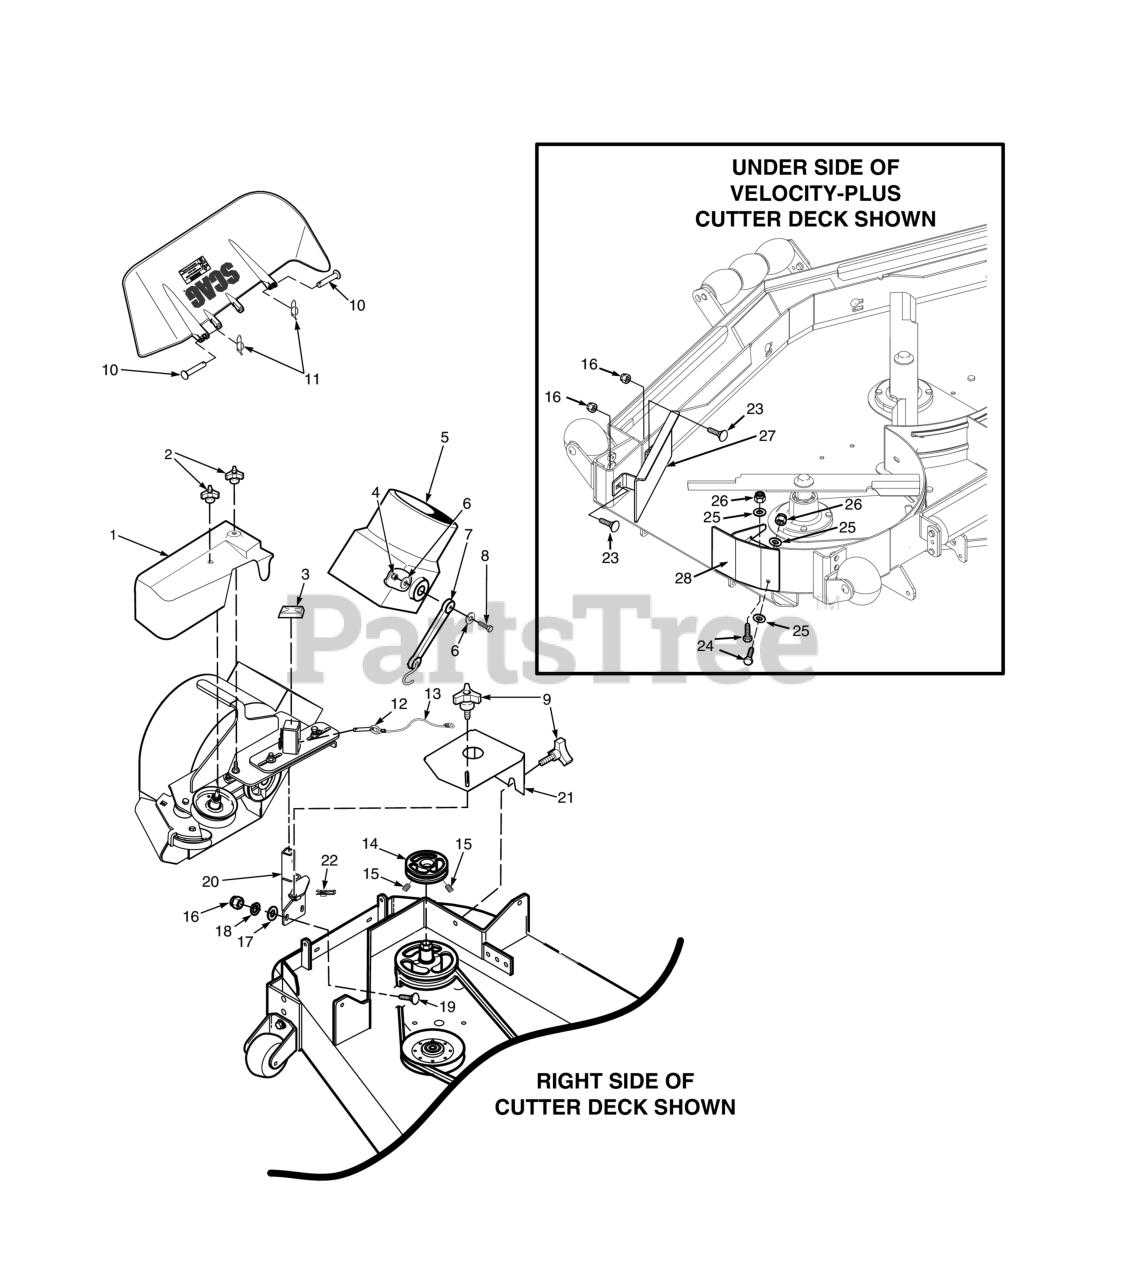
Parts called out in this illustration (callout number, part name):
1	Belt Cover, GC-STT - 61"
2	Wing Nut, 3/8-16 (Small) Top side
3	Cap, Square Vinyl
4	HEX, NUT, ELASTIC STOP LOCK, 1/4-20
5	Adapter, Blower GC-STC,
6	Flatwasher, 1/4" (.312 x .750 x .065")
7	Rubber Strap 7-3/4"
8	SERR. FLG. HEX HEAD CAPSCREW, 5/16-18 X 3/4
9	Knob, w/stud 3/8-16 x 1-1/4"
10	Clevis Pin, 5/16 x 1-1/2"
11	Pin, Rue Cotter 5/16 Dia.
12	Pin, Ring 1/2 x 2-1/4"
13	Lanyard, Deck Height Pin
14	Pulley, 5-1/2" Dia. - 1.125" Bore, (61")
15	Setscrew, Hex Socket Knurl Cup Pt. 5/16 - 18 (nylock)
16	HEX NUT, ELASTIC STOP LOCK, 3/8-16
17	Lockwasher, 3/8" Spring, Kawasaki FX / FT & FT-EFI / B&S 32BV
18	Flatwasher, 3/8" Special (.391 x .938 x .105)
19	SHORT SQ. NECK CARRIAGE BOLT, 3/8-16 X 1-1/4"
20	Mounting Post Weldment, Blower, (61")
21	Belt Cover Assembly, GC-STT-61V w/Cap
22	U-Nut, 3/8-16 (short)
23	Carriage Bolt, 3/8-16 x 1.0"
24	Bolt, Heax Head 5/16-18 x 1" (48V / 52V)
25	Flatwasher, 5/16-.375 x .875 x .083 (35BV & 37BV-EFI)
26	HEX NUT, ELASTIC STOP LOCK, 5/16-18
27	Baffle Weldment - 61" Deck
28	Baffle, Turbo - 61" Deck
